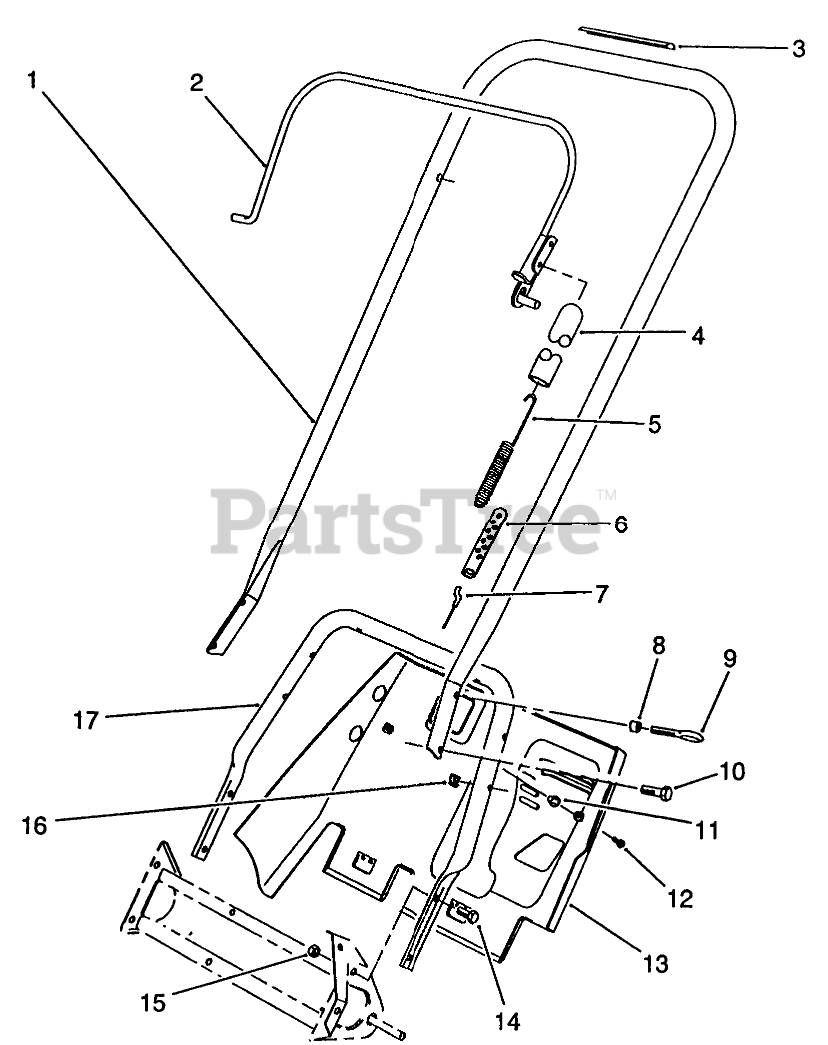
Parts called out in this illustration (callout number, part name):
1	Handle-Upper
2	Bail
3	DECAL - ROTOR DRIVE
4	COVER-SPRING
5	SPRING-CLUTCH
6	ADJUSTER-CABLE, CLUTCH
7	Cable-Clutch
8	SPACER-BLADE, ROTOR
9	EYEBOLT
10	SCREW-HEX HD SLOT
11	EXPANSION TYPE FASTENER
12	SCREW-SHWH, THREAD FORMING
13	LOWER SHROUD
14	SCREW-HH
15	NUT-LOCK, NI
16	TINNERMAN NUT
17	Handle-Lower
